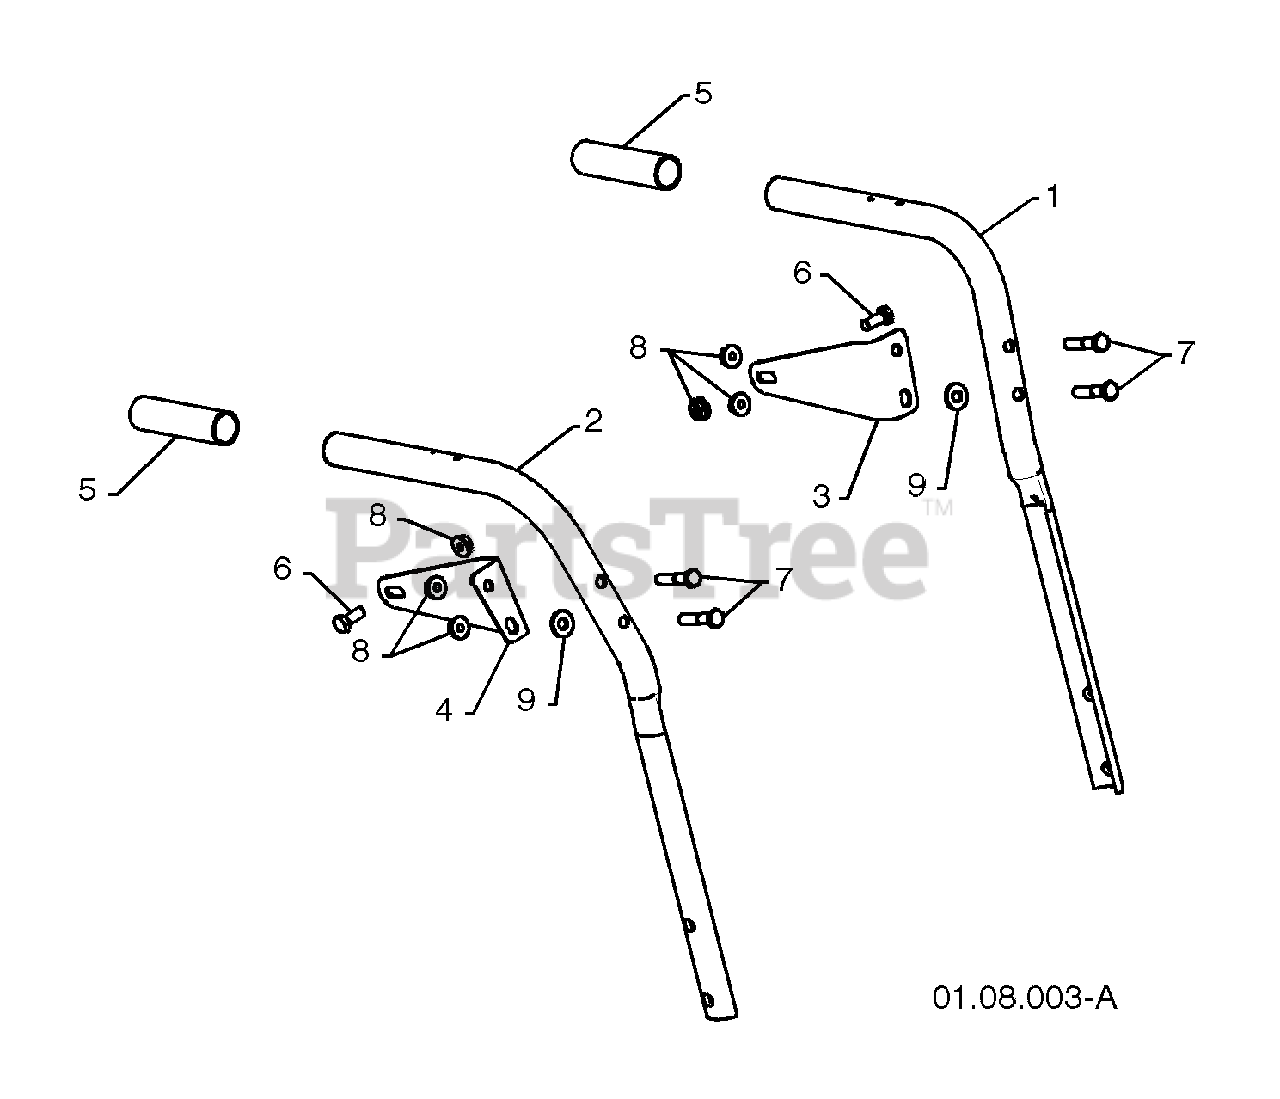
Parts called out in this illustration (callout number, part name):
1	PLOW HANDLE LH
2	PLOW HANDLE RH
3	PANEL BRACKET LH
4	PANEL BRACKET RH
5	HANDLE GRIP
6	SCREW 5/16-18 X .750
7	SCREW 5/16-18 X 1.50
8	NUT 5/16-18
